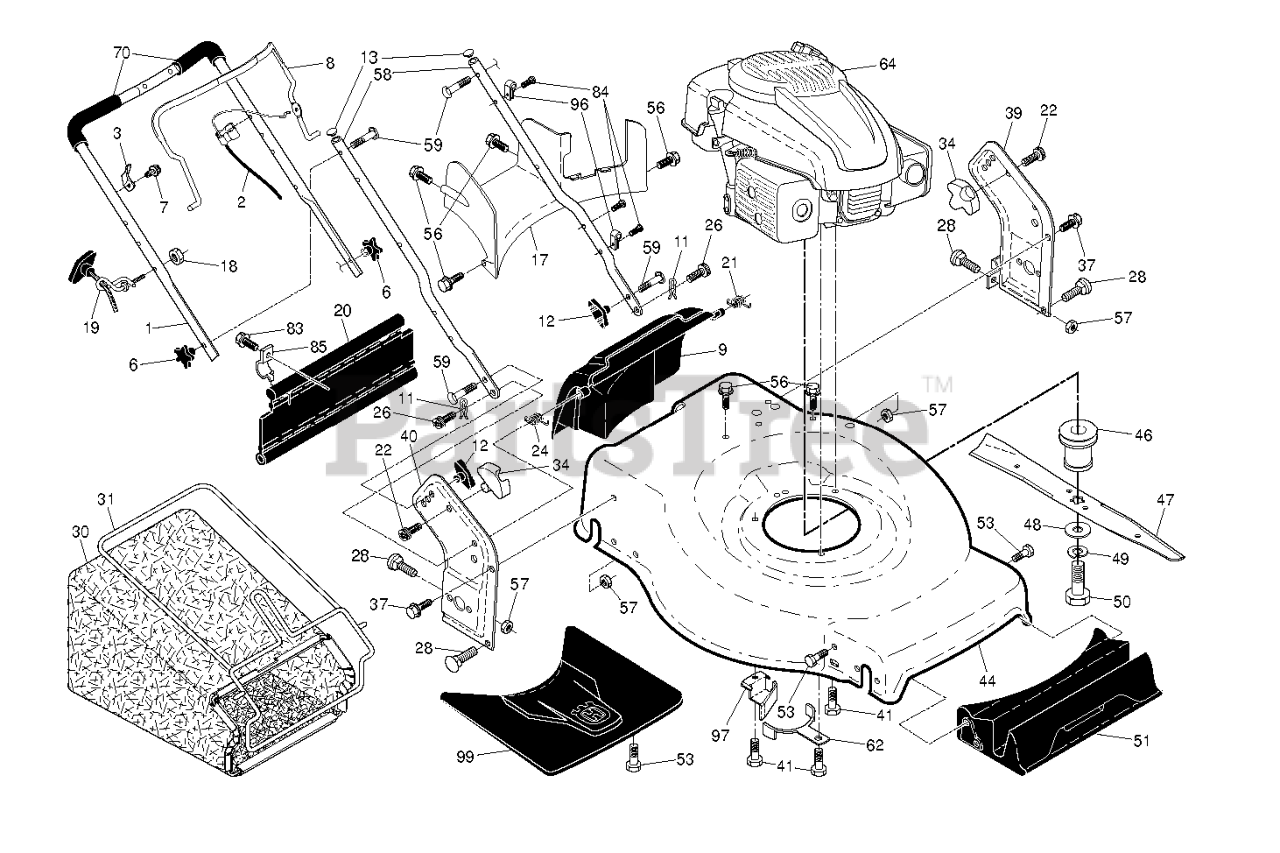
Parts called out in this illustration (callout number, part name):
1	HANDLE.ASM.GRY.W/GRIP
2	CABLE.MZR.RGD.KOHLER.STRT
3	BRACKET.UPSTOP.RT
6	KNOB.HANDLE.PLASTIC.STAR.BLACK
8	BAIL.MZR.EZ2.DSTR.22+.ORG.E
9	DOOR.REAR.ASM.22+.HUSQ.FG/RGD
11	COTTER.HAIRPIN.DOOR/HANDLE.PIV
12	KNOB, DEFLECTOR
13	PLUG.PLASTIC.7/8".14-20.GAUGE
17	RP.BAFFLE.REAR.22+.RGD.PL
18	NUT
19	RB GUIDE.ROPE.STD.BLK.ZIN WSL
20	SKIRT.REAR.22PLUS.RGD/FGD.NEW
21	SPRING.LH.BLACK
22	SCREW.PAN.HEAD.#10
24	SPRING.RH.GRAY
26	SCREW,DOOR/HANDLE.PIVOT
28	BOLT
30	GBAG.A3610247T.SILV.HUSWT.BLUE
31	RB FRAME.GBAG.22PLUS
34	BRACKET.GRASSBAG.ATTACHING.BLK
37	BOLT.5/16HEX.WHS.HD
39	BRACKET.HANDLE.LT.22+.W/DP.GRE
40	RP.BRACKET.ASM.HANDLE.RT.22+.
41	BOLT 3/8-16X1-1/8
44	HOUSING.22+.RWD.WO/PORT.ORANGE
46	ADPTER.BLAD.25M.VS.22PLU.STAR
47	BLADE.22+FUSION.PREM/PREC
48	WASHER,HARDEN
49	LOCKWASHER
50	SCREW, HEX HD 3/8-24 X 1-3/8
51	BAFFLE.FRONT.22PLUS.PLASTIC RP
53	SCREW.HI-LO.5/16 X.75
56	SCREW.HX.13X.750
57	NUT.FLANGE.5/16
58	HANDLE.LOWER.22+BT.2PC.GRY
59	BOLT, HANDLE 5/16-18X1.75
62	BRACKET.KEEPER.BELT
70	GRIP.HANDLE.FOAM.WIDE.(1 SIDE)
83	TAPPING SCREW
84	FASTENER.PUSH.O.250X0.783
85	BRACKET.SKIRT.22+.BZP
96	CLIP.CABLE.BLK
97	BRACKE.BELT.GUIDE.22+
99	COVER.ASM.FRONT.SHROUD.HUSQ.
